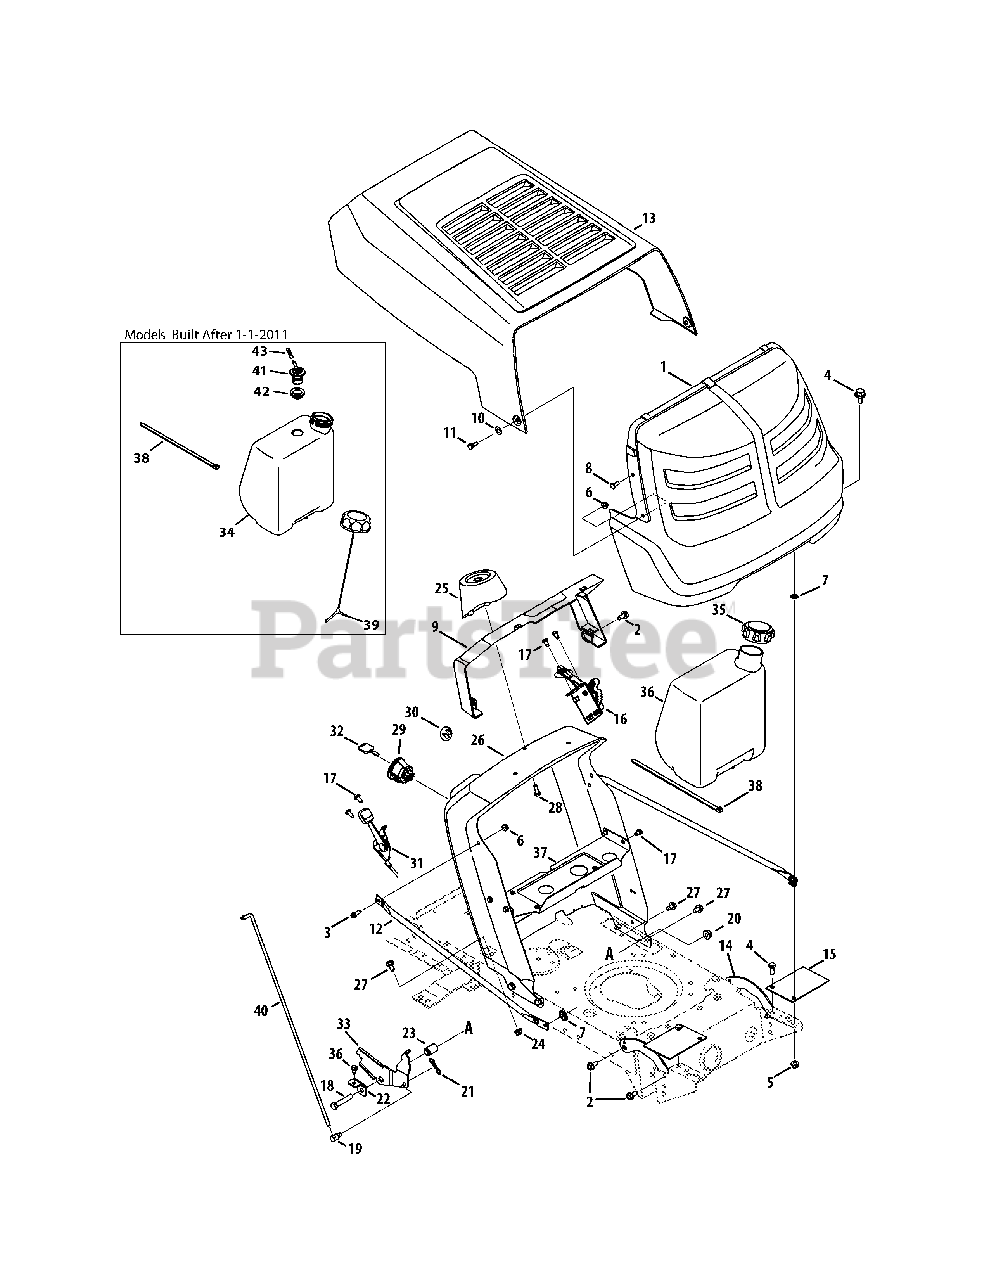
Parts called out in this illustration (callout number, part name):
1	Grill Assembly
2	Screw, Tap, 5/16-18, .750
3	Screw, Tap, 1/4-20, 0.750
4	Hex Screw, 5/16-18, .75
5	Flange Lock Nut, 5/16-18
6	Flange Lock Nut, 1/4-20
7	Nut, push-On, .25 Dia
8	Rivet, flat Head 1/4"
9	Collar, dash, 0/2 Style
10	Washer, Thrust, .375x.70x.030
11	Bolt, Shoulder, .375 X .125
12	Grill Support Rod
13	Hood - Red
13	Hood - Gray
14	Front Pivot Support Bracket
15	Support Bracket
16	6-Speed Control Assembly
17	Screw, Tap, 1/4-20, 0.500
18	Hex Screw, 3/8-16, 2.00, Gr5, Std
19	Adjustable Ferrule, 1/4-20 X 1.00
20	Flange Lock Nut, 3/8-16
21	Bow-Tie Cotter Pin, 72
22	Speed Latch
23	Flange Spacer, .390 X .671 X 1.095
24	Flange Lock Nut, 5/16-18
25	Steering Support
26	Dash, lt-5, No RMC
27	Tap Screw,5/16-18, 0.625
28	Screw, HL, 1/4 Dia. x 0.750
29	Key Switch
30	Choke Plug
31	Throttle/Choke Cable Assembly
33	Speed Latch - No RMC
34	Fuel Tank, 1.36 Gal.
35	Fuel Cap
36	Fuel Tank, 1.50 Gal.
37	Gas Tank Support Braket
38	Cable Tie, 36.0 Long
39	Fuel Cap,2.25"
40	Speed Selector Control Rod
41	Rollover Valve
42	Rubber Grommet, 23 x 3.55
43	Hose Vent
